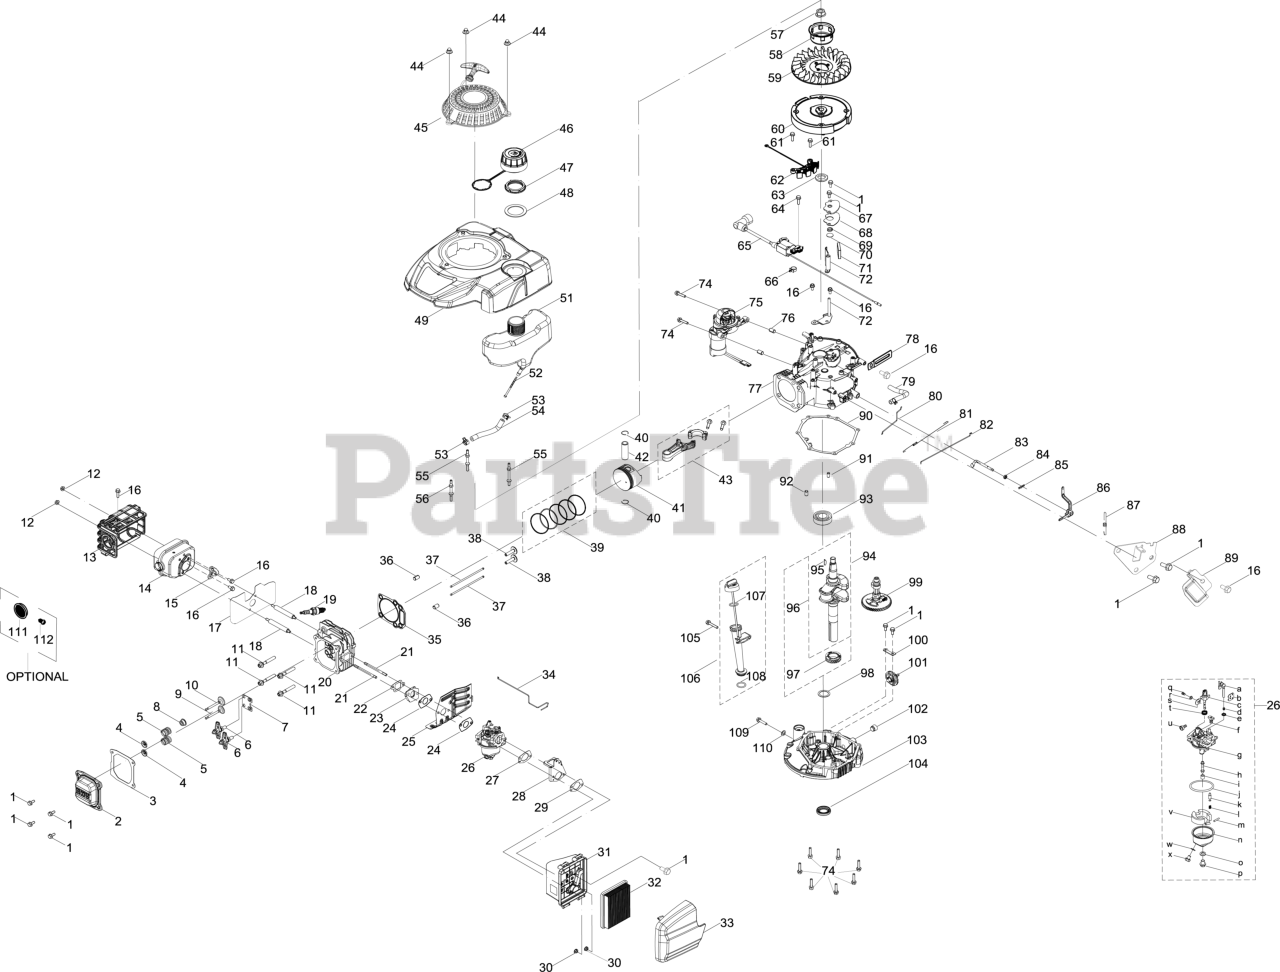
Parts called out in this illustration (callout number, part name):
1	BOLT M6-1 x 14 GR8.8
2	VALVE COVER
3	VALVE COVER GASKET
4	INTAKE VALVE SPRING RETAINER
5	VALVE SPRING
6	ROCKER ARM ASSEMBLY
7	PUSH ROD GUIDE
8	INTAKE VALVE SEAL
9	EXHAUST VALVE
10	INTAKE VALVE
11	SCREW M8 x 54 GR10
12	HEX NUT
13	MUFFLER SHIELD
14	MUFFLER
15	THERMOSTAT
16	BOLT M6-1 x 12 GR8.8
17	MUFFLER GASKET
18	STUD M6-1 x 95
19	SPARK PLUG
20	CYLINDER HEAD
21	CARBURETOR STUD-M6 x 87
22	CARBURETOR GASKET
23	CARBURETOR INSULATOR
24	CARBURETOR GASKET
25	HEAT SHIELD
26	CARBURETOR
27	AIR FILTER BRACKET GASKET
28	AIR FILTER BRACKET
29	AIR FILTER BASE GASKET
30	HEX NUT
31	AIR FILTER HOUSING BASE
32	AIR FILTER
32	Cub Cadet AIR FILTER
32	Genuine Factory Parts AIR FILTER
33	AIR FILTER COVER
34	CHOKE LINKAGE
35	CYLINDER HEAD GASKET
36	PIN (10MMx16MM)
37	PUSH ROD
39	PISTON RING SET
40	PISTON PIN SNAP RING
41	PISTON
42	PISTON PIN
43	CONNECTING ROD
44	ACORN NUT
45	RECOIL STARTER ASSEMBLY
46	FUEL CAP W/TETHER
47	FUEL TANK NUT
48	FUEL TANK UPPER GROMMET
49	ENGINE SHROUD ASSEMBLY
51	FUEL TANK
52	FUEL FILTER
52	Genuine Factory Parts FUEL FILTER
53	HOSE CLAMP
54	FUEL HOSE
55	STARTER/SHROUD REAR STUD
56	STARTER/SHROUD FRONT STUD
57	FLYWHEEL NUT
58	STARTER CUP
59	COOLING FAN
60	FLYWHEEL
61	BOLT M6-1 x 20 GR8.8
62	ALTERNATOR
63	CRANKSHAFT SEAL
64	BOLT M6-1 x 25 GR8.8
65	IGNITION COIL
66	WIRE SUPPORT CLAMP
67	BREATHER COVER PLATE
68	BREATHER GASKET
69	BREATHER VALVE SPRING
70	BREATHER VALVE
71	BREATHER SCREEN
72	AIR VANE
73	AIR VANE BRACKET
74	BOLT-M6-1 x 28 GR8.8
75	ELECTRIC STARTER
76	DOWEL PIN
77	CRANKCASE
78	FLEXIBLE CLAMP
79	BREATHER HOSE ASSEMBLY
80	CHOKE LINKAGE
81	THROTTLE LINKAGE
82	THROTTLE SPRING
83	GOVERNOR ARM SHAFT
84	OIL SEAL
85	COTTER PIN
86	GOVERNOR ARM ASSEMBLY
87	GOVERNOR SPRING
88	COMPONENT BRACKET
89	GOVERNOR SHIELD
90	CRANKCASE COVER GASKET
91	DOWEL PIN 7 X 14
92	DOWEL PIN 9 X 14
93	BEARING
94	CRANKSHAFT ASSEMBLY
95	WOODRUFF KEY
96	CRANKSHAFT
97	DRIVE TIMING GEAR
98	THRUST WASHER
99	CAMSHAFT ASSEMBLY
100	GOVERNOR GEAR MOUNTING PLATE
101	GOVERNOR GEAR/SHAFT ASSEMBLY
102	OIL DRAIN PLUG
103	CRANKCASE COVER
104	LOWER CRANKSHAFT OIL SEAL
105	BOLT M6-1 x 35 GR8.8
106	OIL DIPSTICK ASSEMBLY
107	O-RING
108	O-RING
109	OIL DRAIN PLUG
110	FLAT WASHER
111	SPARK ARRESTOR
112	SCREW M3.5 x 9.5
